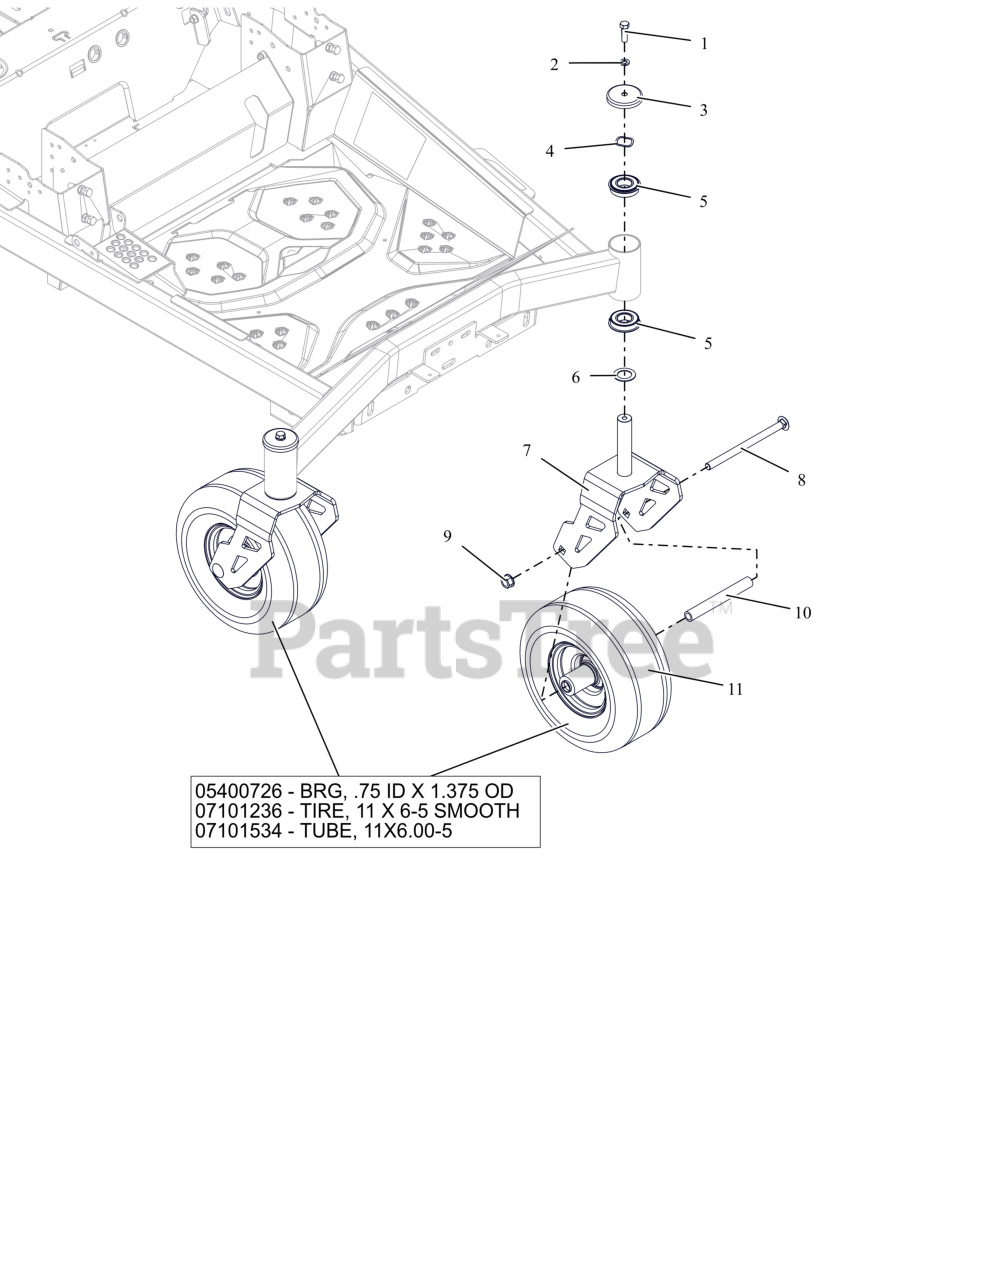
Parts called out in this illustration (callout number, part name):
1	BLT- HEX .38-16X1.25 G5 ZB500
2	WSHR-LK-REG .375X.094 ZB500
3	SHIELD- AXLE BEARING
4	WSHR-WAVE 1.0X1.25X.028 .145FH
5	BEARING, BALL -2.000 OD X 1.000 ID X .5625 W/RING
6	WSHR-HRD-THRS 1.007X1.542X.062
7	WMT-CASTER FOR-MY23
8	BLT-RHSN .50-13X7.50 G5 ZCC NS
9	NUT-LK-CTR-FLG .500-13 GG ZCC
10	SPACER, FRONT WHEEL (WIDE 6.0)
11	TIRE/WHEEL ASSY 11X6-5
11	BRG, .75 ID X 1.375 OD
11	TIRE, 11X6-5 Smooth
11	VALVE STEM ASS'Y
11	Tire Tube, 11/6.0-5
